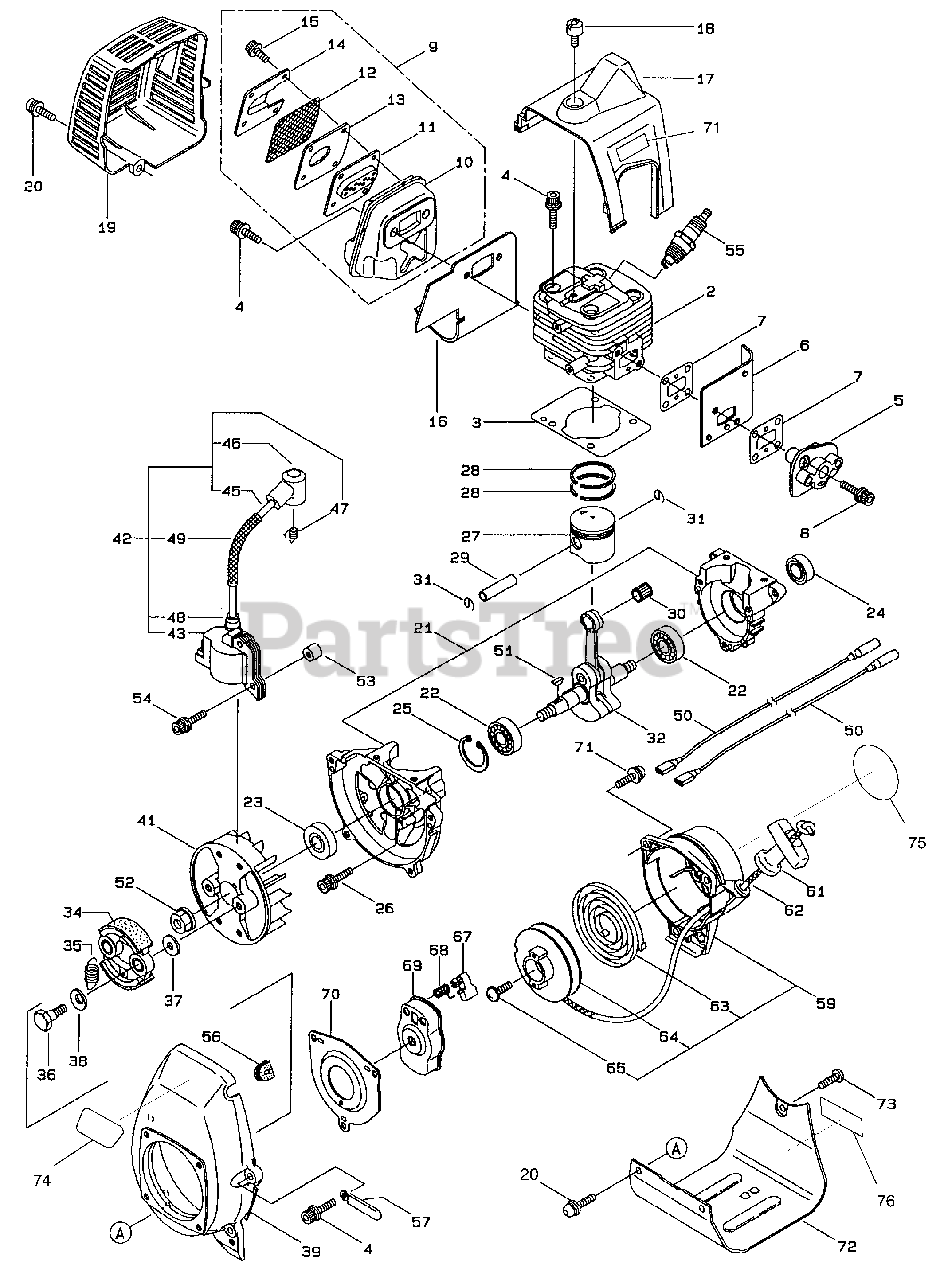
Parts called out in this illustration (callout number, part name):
2	Cylinder
4	Cap Screw
5	Insulator
6	Air Duct
8	Cap Screw
9	Muffler Assembly (Incl. Ref. #10-15)
15	Cap Screw
17	Cylinder Cover
19	Muffler Cover
20	Cap Screw
21	Crankcase
23	Oil Seal
24	Oil Seal
25	Snap Ring
26	Cap Screw
28	Piston Ring
29	Piston Pin
30	Bearing-Needle
31	Clip-Piston
32	Crankcase-Connector Rod Assembly
34	Clutch Shoe
35	Spring-Clutch
38	Wave Washer
39	Fan Cover
41	Rotor-Fan
42	Ignition Coil Assembly (Incl. Ref. #43-49)
45	Spark Plug Wire
46	Plug Boot
47	Connector
49	Insulator
50	Wire-Coil Ground
51	Woodruff Key
52	Nut-Rotor
54	Cap Screw
55	Spark Plug (NGK BPM6Y)
59	Recoil Assembly (Incl. Ref. #60-65)
61	Starter Grip
62	Starter Rope
63	Spiral Spring
68	Return Spring
69	Pawl Case
71	Decal-Warning
74	Decal-Toro
75	Decal-Toro (Round)
76	Decal-Serial
